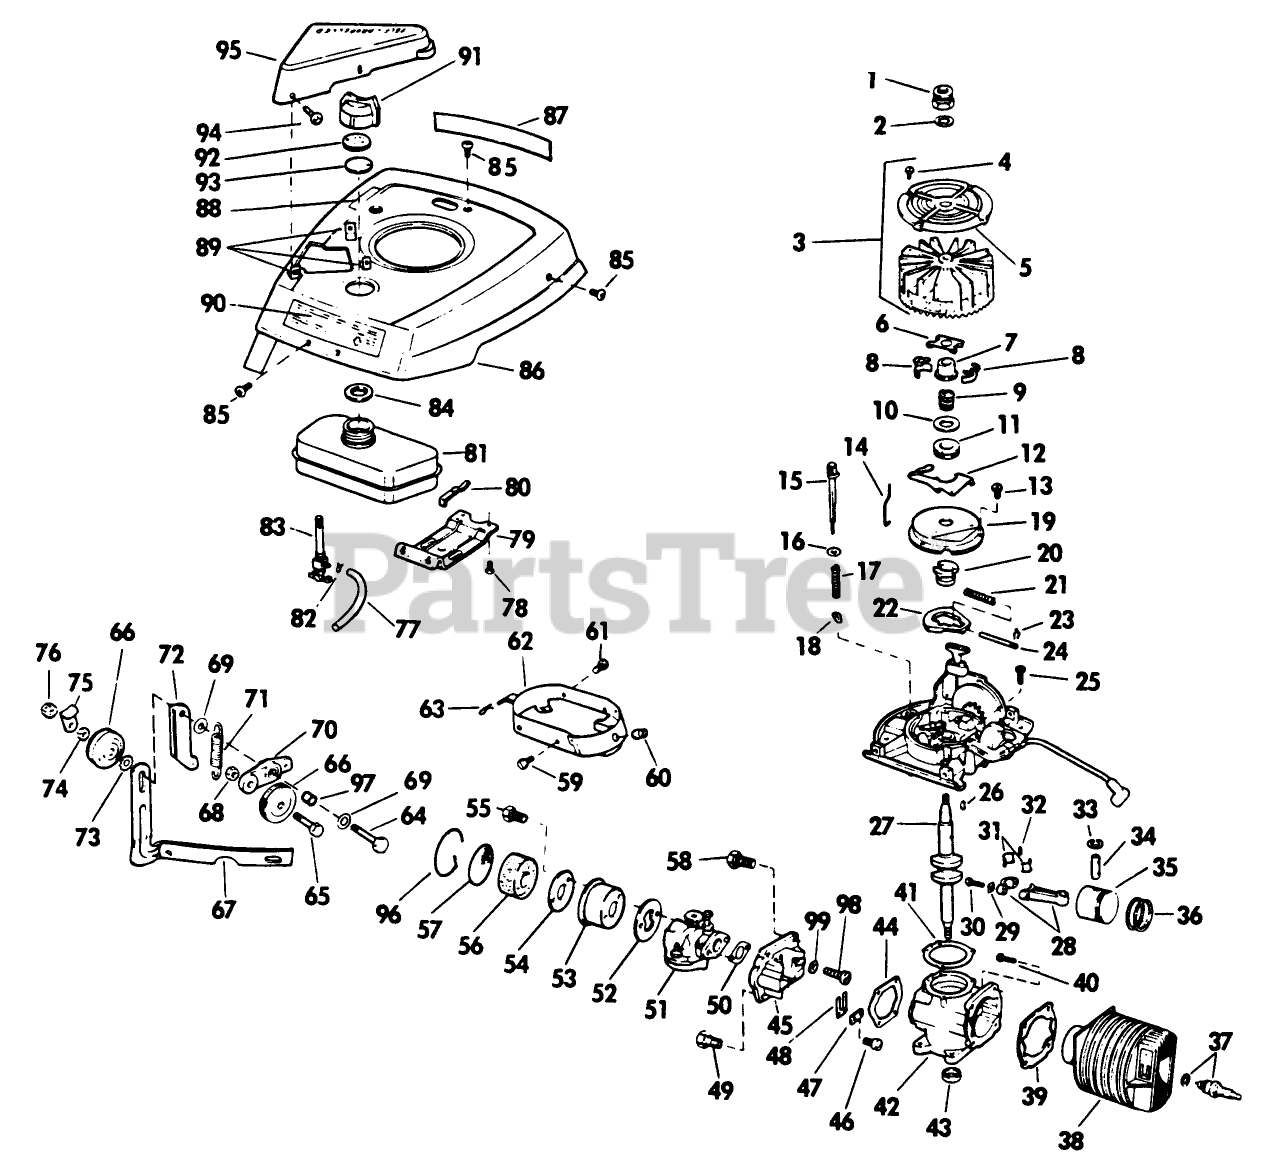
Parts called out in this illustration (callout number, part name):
1	PULLEY
3	Flywheel Screen Assy.
4	SCREW F
6	YOKE S
7	COLLAR S
11	THRUST COLLAR S
12	LEVER-GOVERNOR S
13	SCREW S
14	ROD S
17	SPRING S
19	DUST COVER S
20	SPARK ADV. S
21	SPARK ADV. SPRING S
22	FLYWEIGHT S
23	SPARK ADJ. SPRING
24	PIN,SPARK ADV. S
25	SCREW S
26	KEY
30	SCREW
31	LINER ASM
33	RING-RETAINING
37	Spark Plug and Gasket
39	GASKET S
41	GASKET S
44	GASKET S
45	REED PLATE AY. S
47	PLATE-BACKUP, REED
49	SCREW S
50	GASKET S
52	GASKET S
54	BACK-UP PLATE
56	ELEMENT
58	SCREW S
59	SCREW S
60	NUT-CLIP
66	IDLER PULLEY
68	LOCKNUT E
76	LOCKNUT E
78	SCREW S
80	SPRING
82	CLAMP - HOSE S
83	VALVE&SCREEN SM
85	SCREW S
91	FUEL CAP AY S
92	Gasket
93	BAFFLE - FOAM SM
95	BELT COVER AY
96	CLIP
99	Seal
